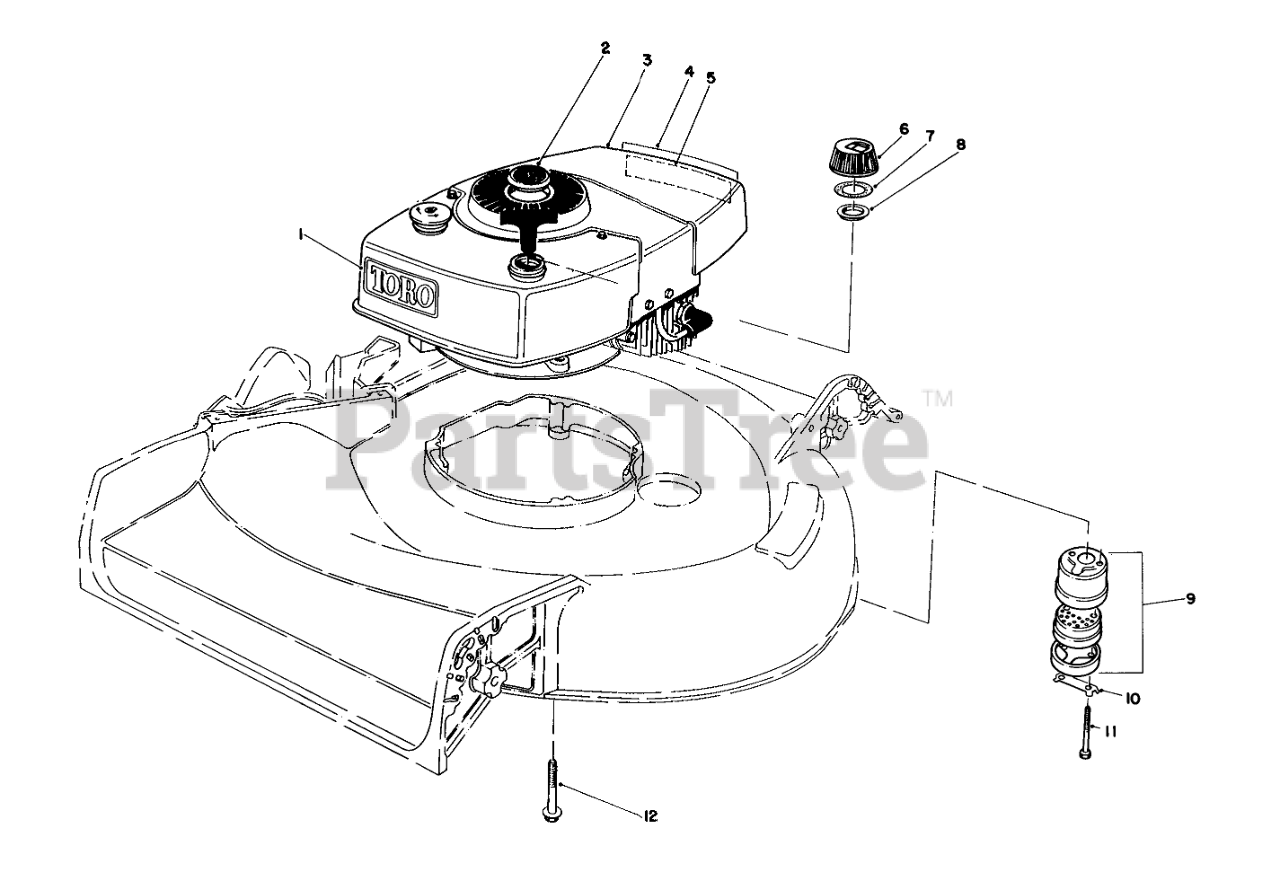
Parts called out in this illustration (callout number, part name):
1	Decal Tow
2	Plug Button
3	Engine
4	Decal-Primer
5	Decal Maintenance
6	Fuel Cap Assembly (Incl. Ref. #7 & 8)
7	GASKET
8	GAS CAP BAFFLE
9	Muffler Assembly (Incl. Ref. #10 & 11)
10	CLIP - LOCKING
11	SCREW-HH
12	3/8-16 X 2-3/4 CAPSCR
